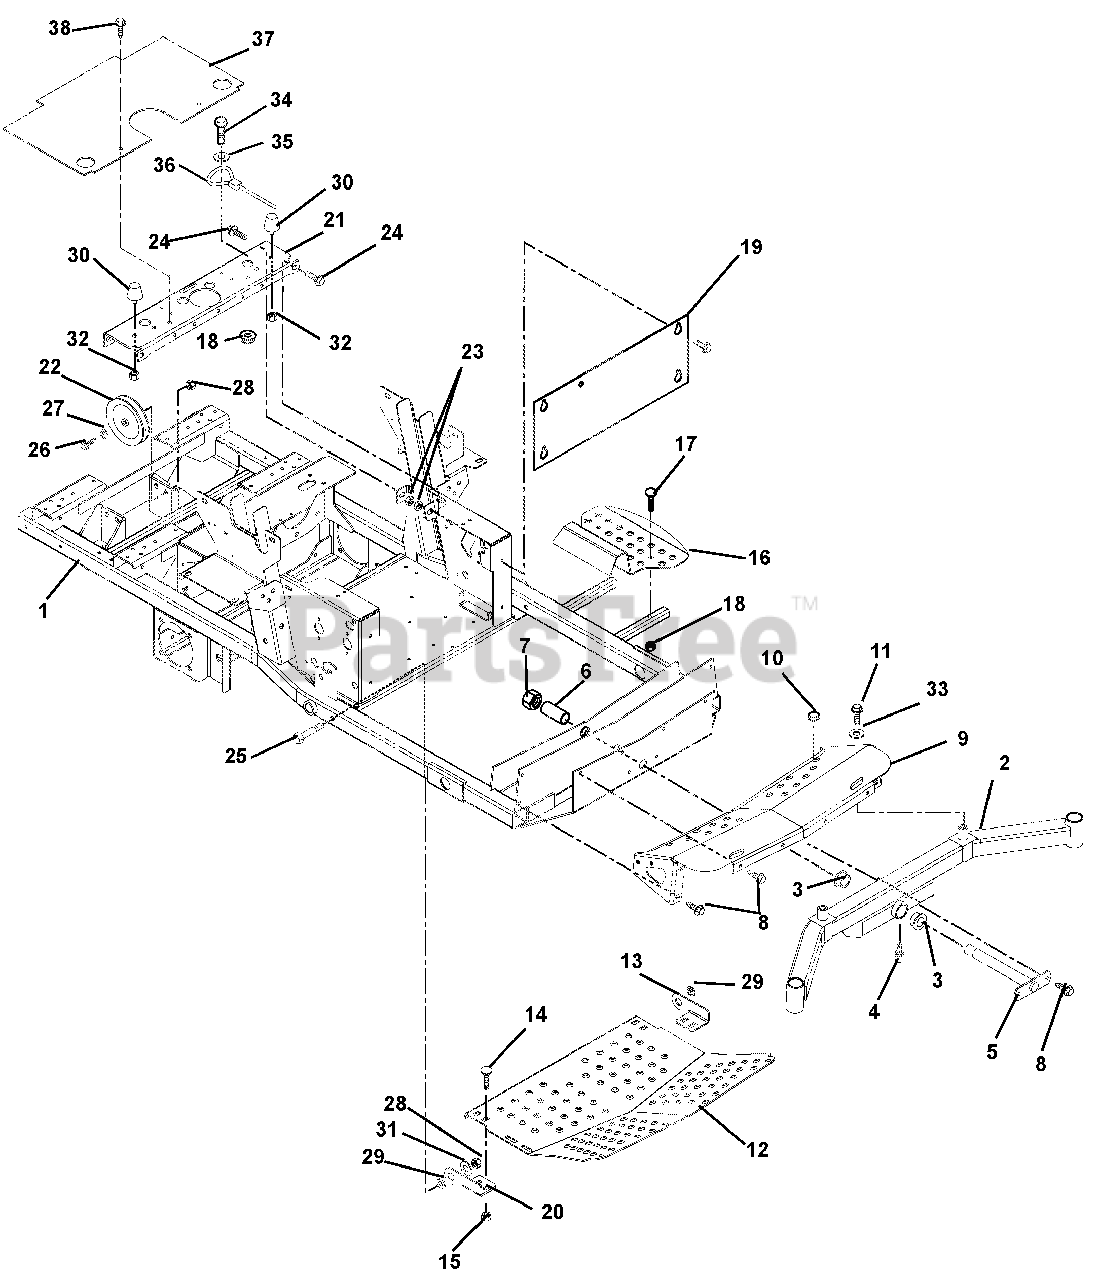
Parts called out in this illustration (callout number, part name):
1	WMT, LIQUID COOLED FRAME - BLK
2	WMT, FRONT AXLE
3	BSHG-FLG1.020X1.385X.75X1.75NY
4	FTG-LUBE .25-28X.256 YWZC
5	PIN - AXLE
6	SPACER 1.009 X 1.250 X 4.23
7	NUT-LK-NYL 1.0-14 YWZC
8	@SCR-TAP .38-16X.75 HWH TR YWZ
9	WMT, AXLE COVER
10	BUTTON BUMPER
11	BLT-HEX .50-20X1.00 GR5 YWZC
12	PANEL - INSPECTION (RED)
13	HINGE, FOOTBOARD LH
14	@BLT-RDHDSQNK .38-16X1.00 G5YZ
15	@NUT-LK-TOP-FLG .38-16 YWZC
16	STEP, INGRESS (BLACK)
17	@BLT-RDHDSQNK .31-18X1.75 G5YZ
18	@NUT-LK-TOP-FLG .31-18 YWZC
19	PLATE - KICK (RED)
20	HINGE, FOOTBOARD RH
21	CHANNEL, CROSS (BLACK)
22	PLY-V 6.0 X .500 ID DBL BRG.
23	NUT-RTNR .375-16X.37
24	BLT-SERHFWH .375-16X1.0 YWZC
25	@BLT-HEX .50-13X3.25 GR5 YWZC
26	@BLT-HEX .50-13X2.25 GR5 YWZC
27	WSHR-FL-STL .505X.880X.072 YWZ
28	@NUT-LK-TOP-FLG .50-13 YWZC
29	BSHG-FLG .515X.750X.285X1.120
30	BUMPER, RUBBER CONE,STUD MOUNT
31	@WSHR-FL-STL.563X1.38X.109YWZC
32	@NUT-SPNLK-FLG .312-24 YWZC
33	WSHR-FLT .640X1.75X.250 YWZC
34	@BLT-HEX .31-18X1.00 GR5 YWZC
35	WSHR-FL-STL .328X1.0X.094 YWZC
36	CABLE, SEAT PROP.
37	GUARD - GRASS
38	@SCR-TAP .38-16X.75 HWH TR YWZ
